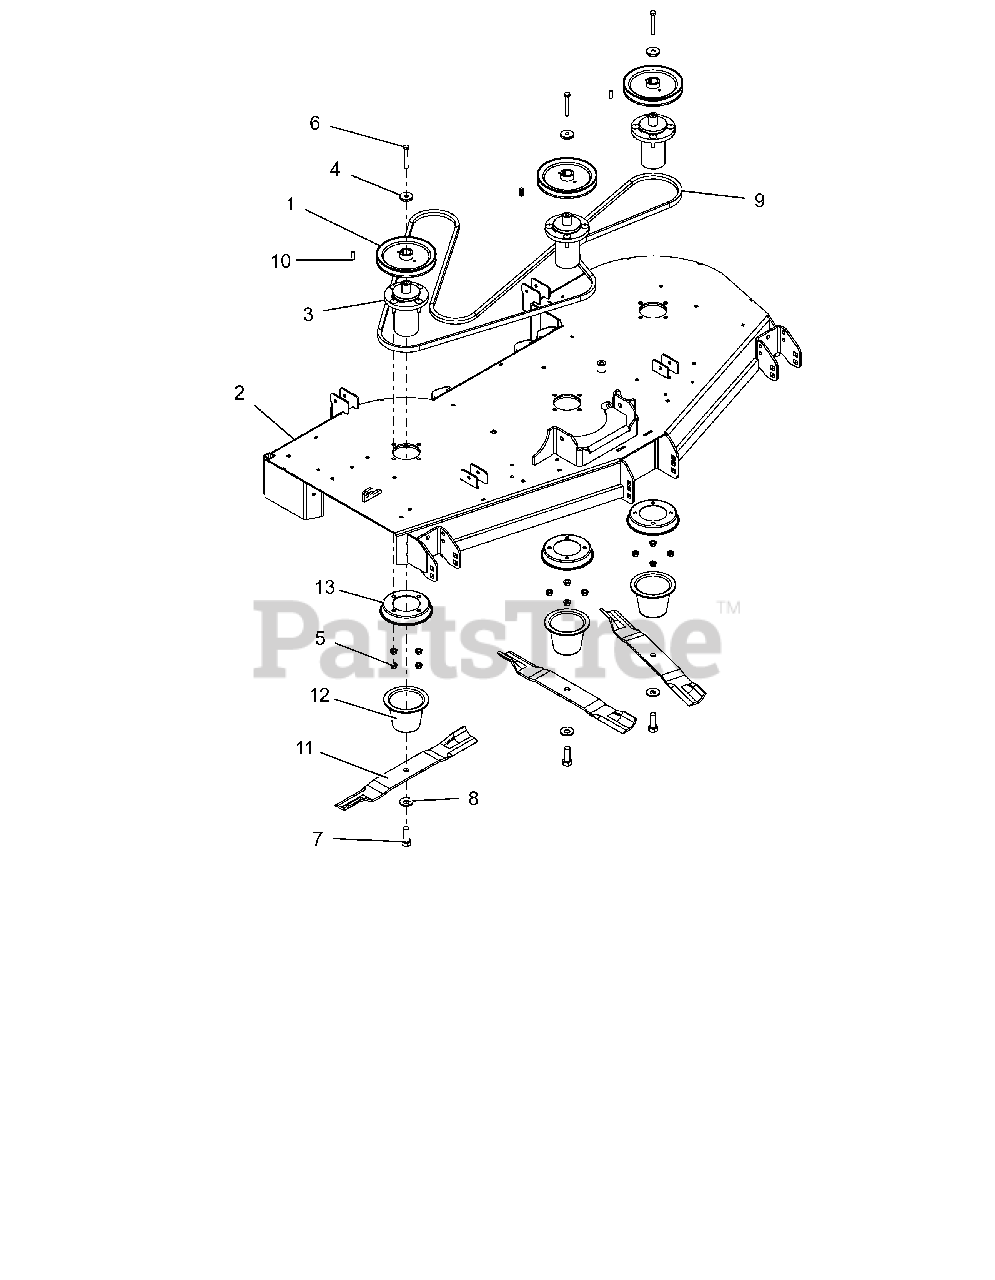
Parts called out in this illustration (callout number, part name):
1	PULLEY, 1.00 ID X 6.75 OD
2	KIT, 60" MOWER DECK W DECALS
3	ASM, ALUM SPINDLE
4	RETAINER, SHEAVE
5	NUT-LK-CTR-FLG .38-16 YWZC
6	BLT-HEX .38-16X1.0 GR8 YZ EP30
7	BLT-HEX .62-18X1.75 GR8 YWZC
8	WSHR-BLVL .669X1.535X.138
9	BELT, B-SECTION EPDM RAW EDGE
10	KEY, SQ .25X.25X1.00 RC 40-50
11	BLADE, MOWER (20.50")
12	GUARD, SPINDLE LOWER
13	GUARD, SPINDLE TOP
